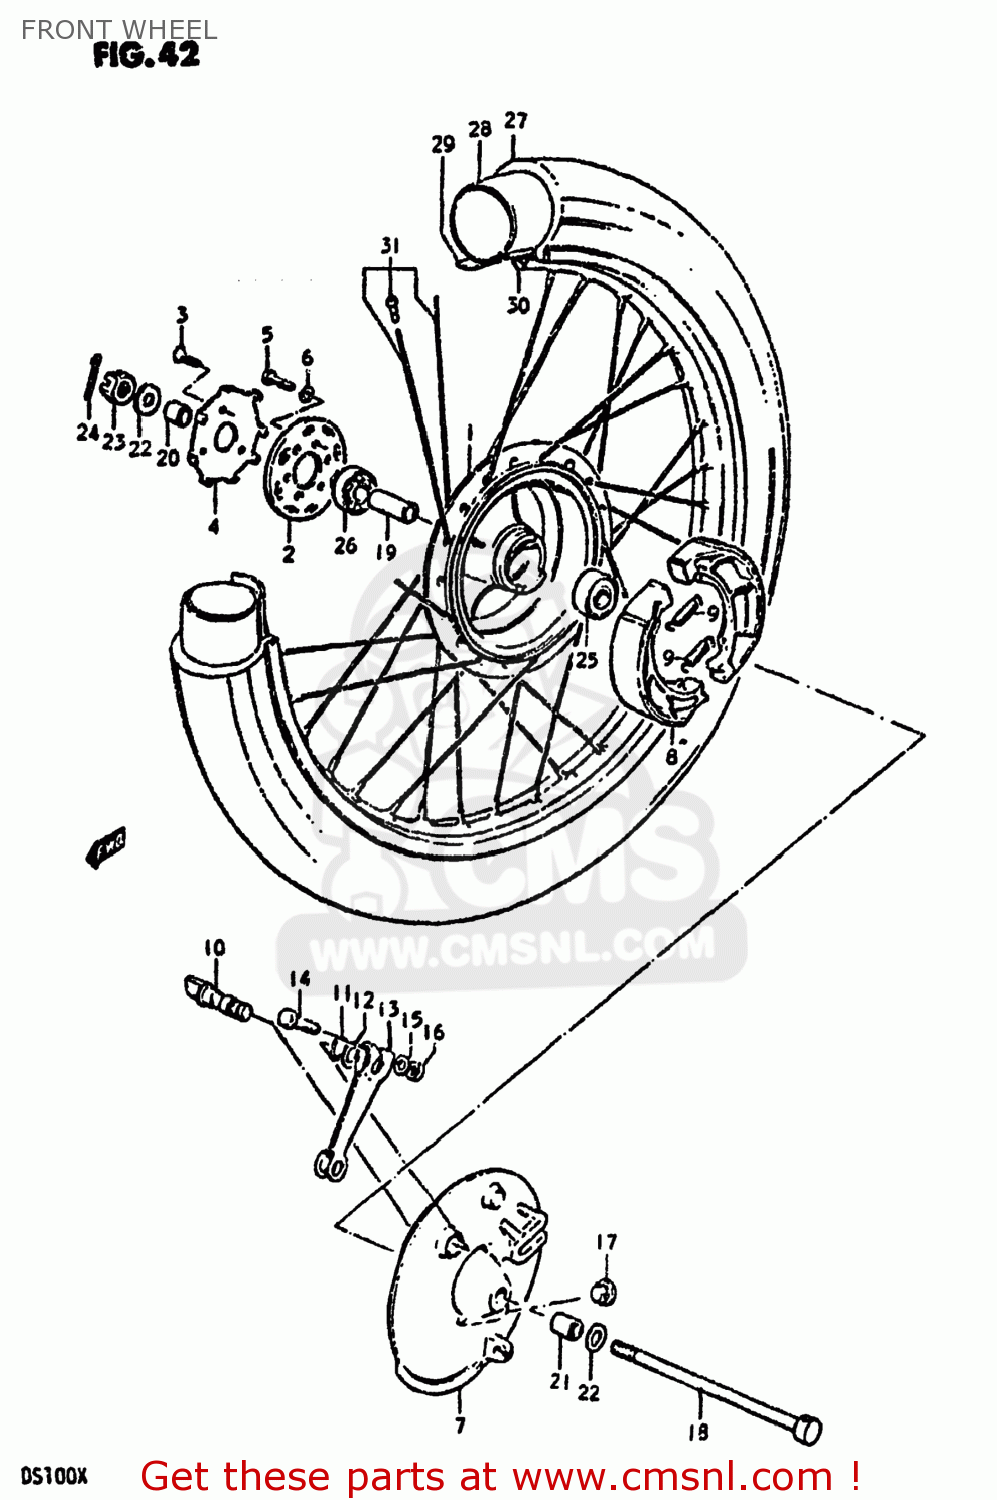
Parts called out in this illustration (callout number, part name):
1	HUB,FR WHEEL
2	FLANGE,FR HUB,R
3	SCREW
4	RETAINER,FR HUB BEARING,R
5	BOLT, UPPER
6	LOCK WASHER
7	PANEL,FRONT HUB
8	SHOE,BRAKE
9	SPRING(L:34)
10	CAM,FRONT BRAKE
11	O-RING (D:2.4 ID:13.8)
12	WASHER (14.5X22X1.6)
13	LEVER,FR BRAKE CAM
14	BOLT(6X33)
15	WASHER
16	NUT
17	CAP(OD:17)
18	AXLE,REAR
19	SPACER (12.6X19X52)
20	SPACER (12.2X19X18.5)
21	SPACER(12X20X34.5)
22	WASHER
23	NUT 12MM
24	COTTER PIN
25	BEARING
26	BEARING, RH
27	TIRE,FRONT
28	TUBE 2.75-19 070-483MM
29	PROTECTOR,WHEEL,INNER
30	RIM,FR WHEEL
31	SPOKE SET,FRONT
